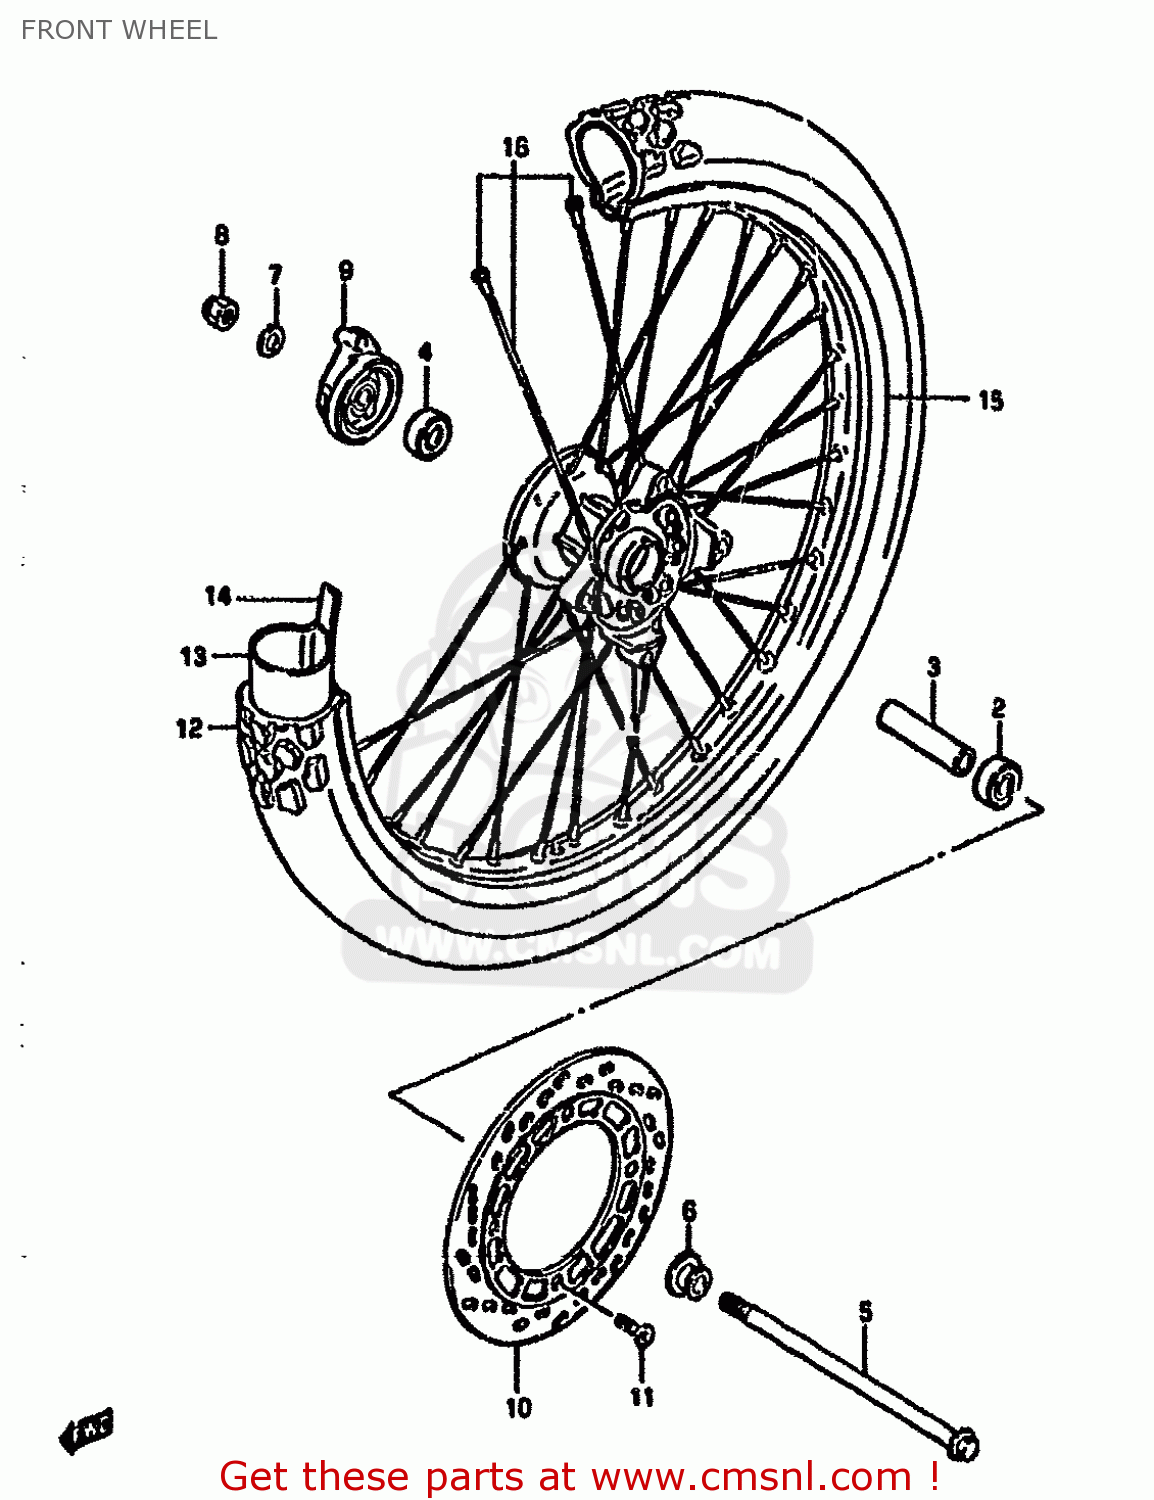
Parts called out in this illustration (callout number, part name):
1	HUB,FRONT
2	BEARING (12X32X10)
3	SPACER (12.6X19X60.5)
4	BEARING
5	AXLE,FRONT
6	SPACER,FRONT AXLE,RIGHT
7	WASHER
8	NUT (12MM)
9	BOX ASSY,SPEEDOMETER GEAR
10	DISC,BRAKE
11	BOLT,BRAKE DISC
12	TIRE,FRONT
13	TUBE
14	PROTECTOR,WHEEL,INNER
15	RIM,FRONT WHEEL
16	SPOKE SET,FRONT
